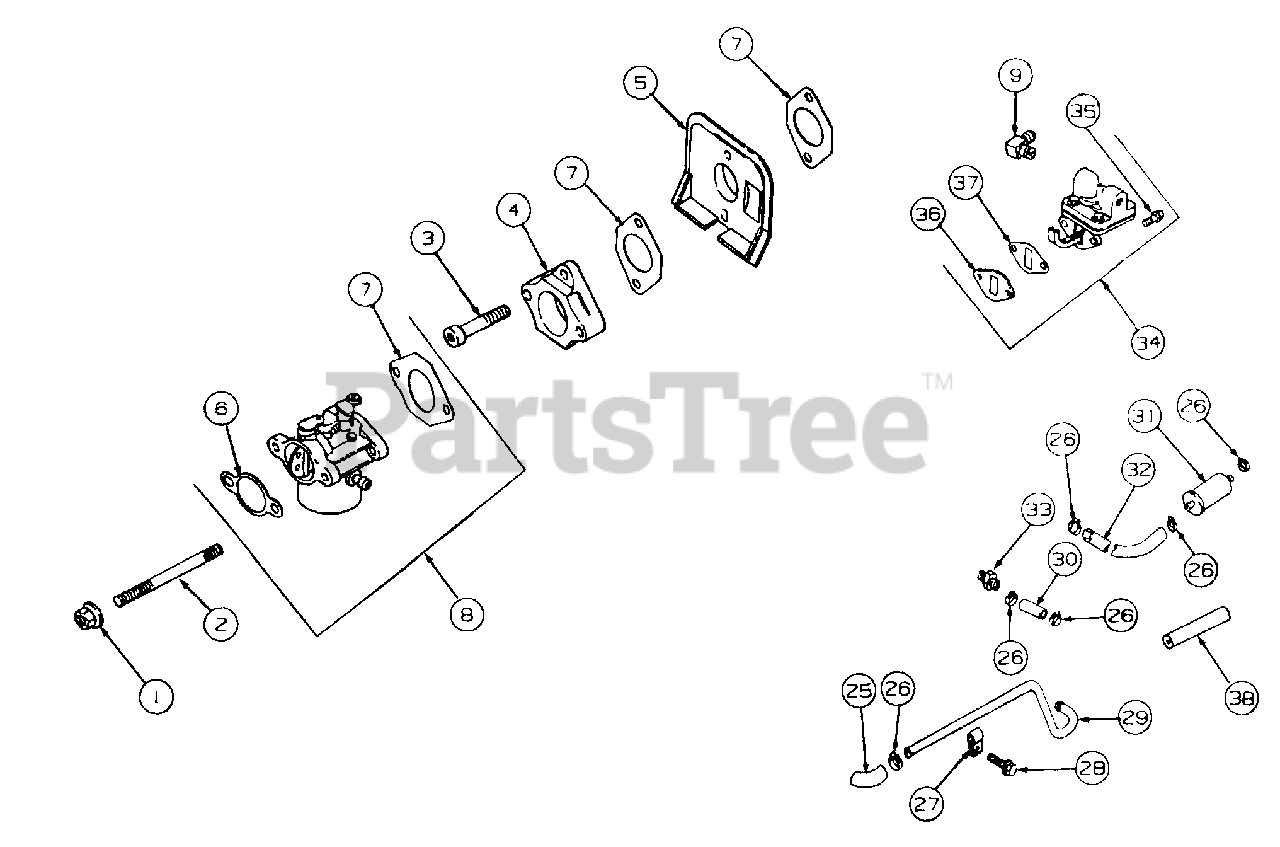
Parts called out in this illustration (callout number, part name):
1	Nut, Hex Flange, M6 x 1.0
2	Stud, Carburetor, M6 x 1.0 x 116
3	Screw, Socket Cap, M6 x 1.0 x 35
4	Adapter, Carburetor
5	Deflector, Heat
6	Gasket, Air Filter
7	Gasket, Carburetor
8	Kit, Carb w/Gskts
9	Connector, Hose, 90°.
25	Line,90° Fuel
26	Clamp, Fuel Line
28	Screw, Hex Flange, M5 x .8 x 10
29	Line, Metal Fuel
30	Line, Fuel, 1 1/4
31	Filter, Fuel
32	Line, Fuel, 5"
33	Connector, Straight Hose
34	Kit, Fuel Pump
35	Screw, Hex Flange, M6 x 1 x 20
36	Spacer, Fuel Pump
37	Gasket, Fuel Pump
38	Insulation Fuel Line
